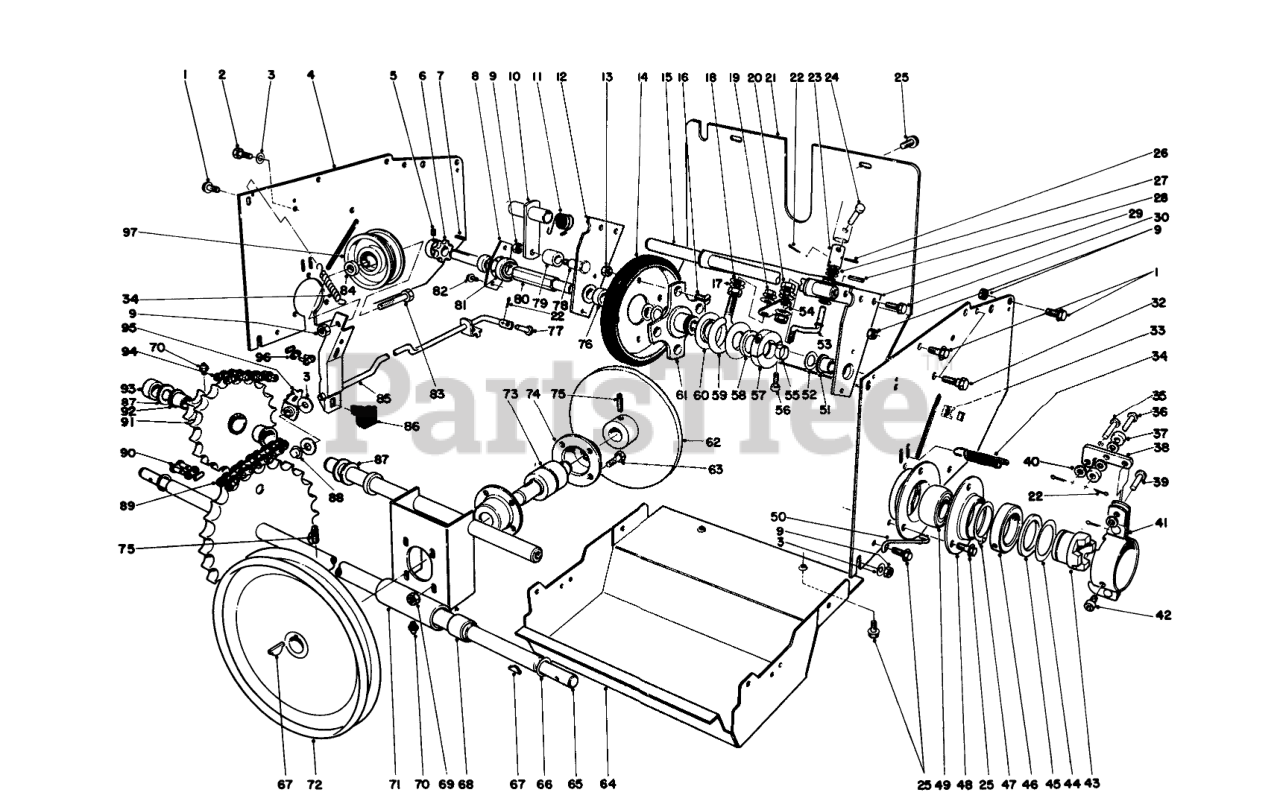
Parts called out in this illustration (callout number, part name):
1	SCREW-HH
2	SCREW-HHFTF
3	WASHER-FLAT
4	Side Plate Drive
5	SCREW-HSH
6	SPROCKET
8	BEARING CUP
9	NUT-HEX
10	CHAIN TENSION ARM WA
11	TORSION SPRING
12	HEX SHAFT MOUNT R
13	Nut
14	FRICTION WHEEL
15	Bracket Dead Shaft
16	5/16-18X5/8 FLT HD MS
17	Washer
18	WASHER-SPRING
19	NUT-LOCK, FLANGE
20	Nut
21	REAR COVER R
22	PIN-COTTER
23	U JOINT TUBE
24	CLEVIS PIN
25	SCREW-HWH
26	PIN-SPRING
27	Clevis Pin
28	PIN-ROLL
29	Hex Shaft Mounting (Incl. Ref. #51)
30	SCREW-HWHTF
32	SHOULDER SCREW
33	Retained Nut
34	EXTENSION SPRING
35	PIN-CLEVIS
36	PIN-CLEVIS
37	CLUTCH ROLLER
38	CLUTCH CAM ARM
39	PIN-CLEVIS
40	WASHER-FLAT
41	CLUTCH MT BRKT ASM
42	Hex Socket Capscrew
43	WHEEL CLUTCH
44	THRUST WASHER
45	THRUST BEARING
46	CLUTCH MOUNT COLLAR
47	RING-RETAINING, EXTERNAL
48	BEARING FLANGE
49	BEARING
50	CLUTCH RETAINER
51	BUSHING
52	WASHER-FLAT
53	CONNECTION ROD
54	SHIFT ROD PIVOT
55	SPLIT SPACER
56	SCREW-HSH
57	Collar
58	WASHER-THRUST
59	SLIDER RING COLLAR
60	SLIDER RING
61	TRACTION DISC HUB
62	Friction Plate
63	SCREW-HH
64	LOWER SHIELD R
65	AXLE SHAFT WA
66	WASHER
67	KEY-WOODRUFF
68	BUSHING
69	NUT-KEPS
70	FITTING-GREASE
71	Bulkhead (Incl.Ref. #68)
72	Pulley
73	Friction Plate Shaft
74	HOUSING BEARING
75	Set Screw
76	SPACER
77	PIN-CLEVIS
78	SHOULDER BOLT
79	CHAIN TENSION ROLLER
80	FRICTION WHEEL SHAFT
81	BEARING
82	SCREW
83	SCREW-HH
84	Spacer
85	Auger Brake Assembly (Incl. Ref. #86)
86	Brake Pad
87	WASHER-THRUST
88	Pushnut
89	ROLLER CHAIN
90	LINK-CHAIN
91	Sprocket (Incl.Ref. #70 & 92)
92	3/4ID X 3/4LG BSHG
93	SPACER-IDLER
94	1/4 X 42 CHAIN W/LINK
95	Bracket-Clutch
96	LINK-CONNECTING
97	Idler Pulley
